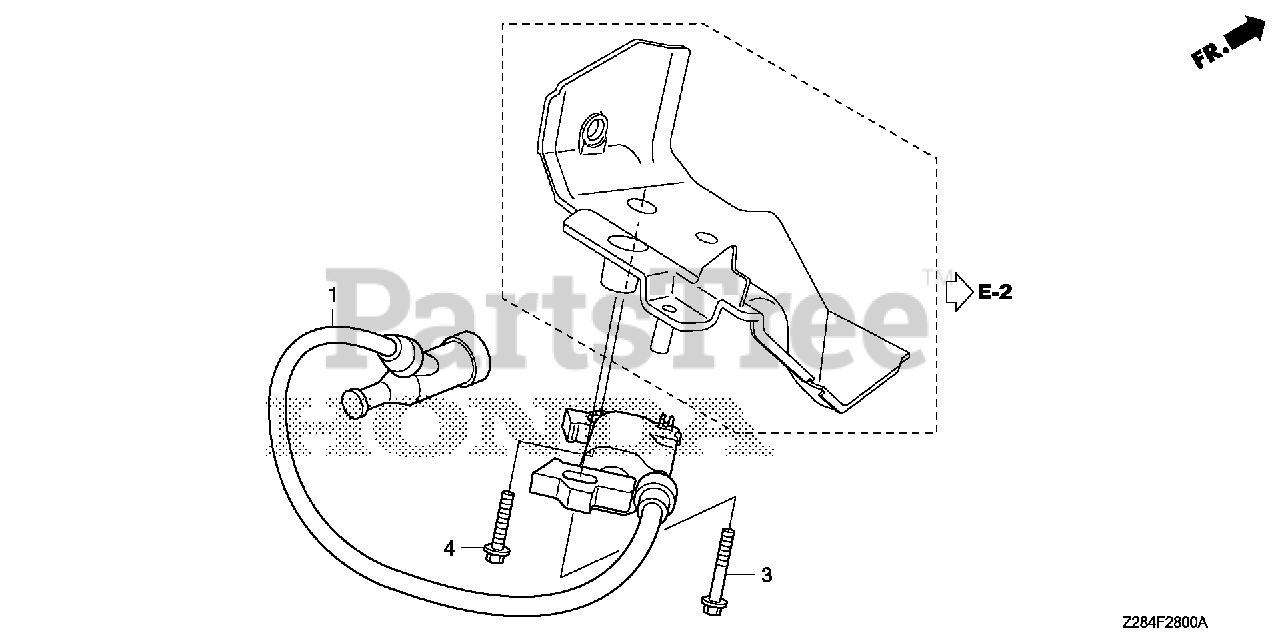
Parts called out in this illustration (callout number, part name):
1	COIL ASSY., IGNITION
3	BOLT, FLANGE (6X35)
4	BOLT, FLANGE (6X20)
